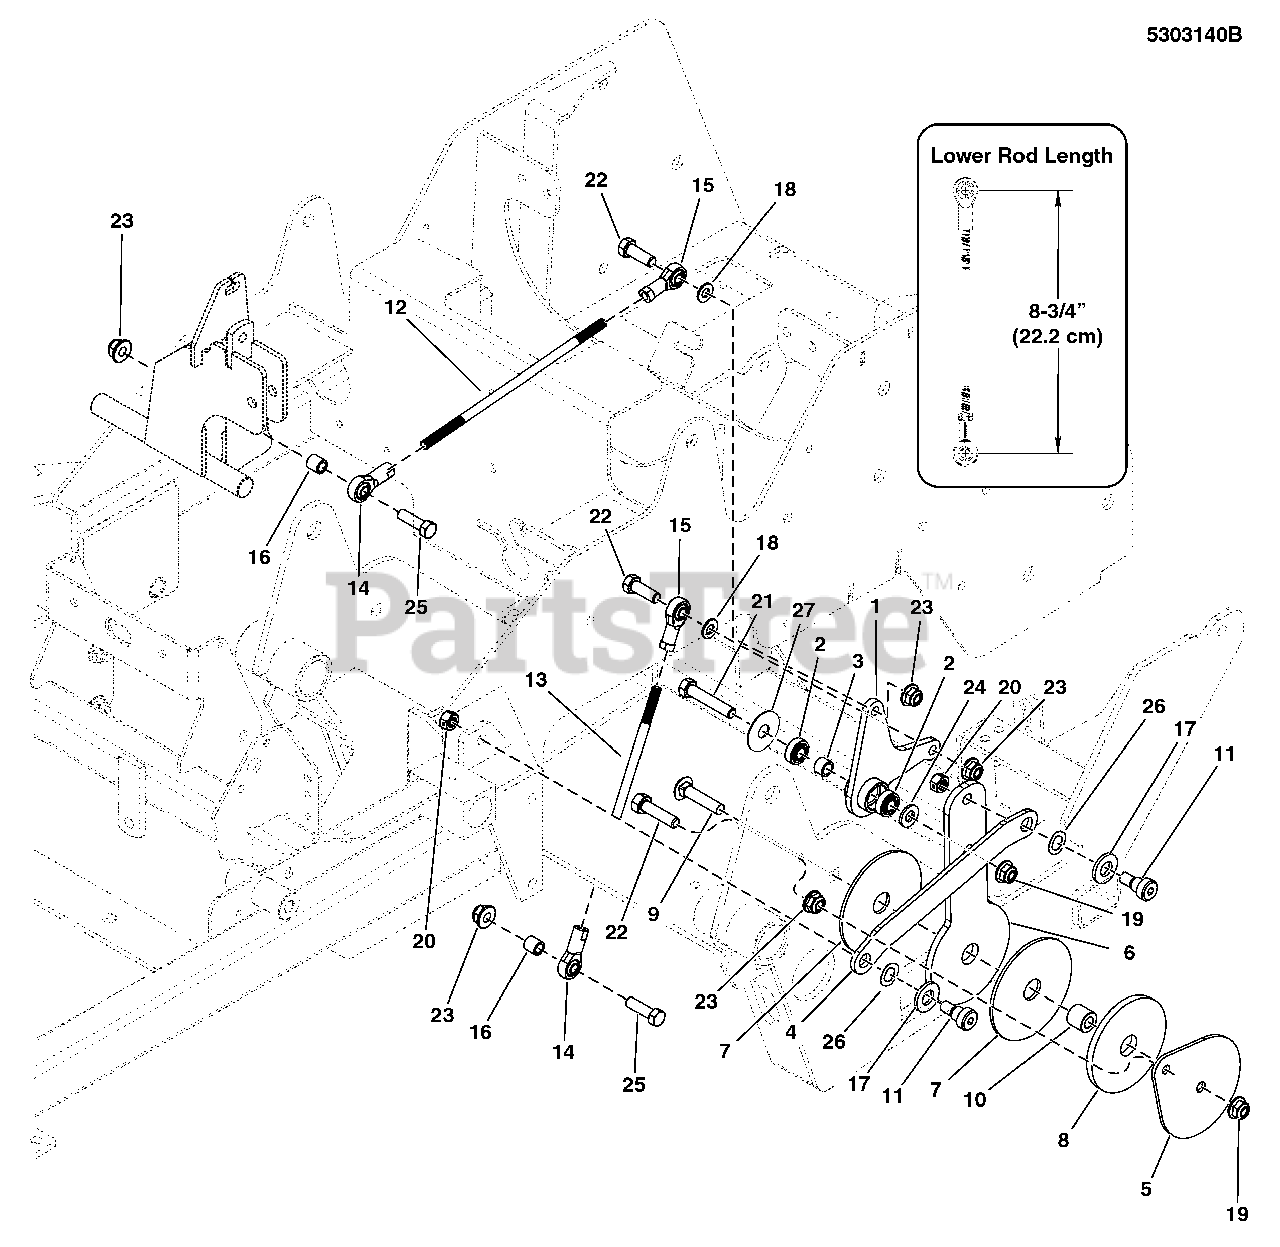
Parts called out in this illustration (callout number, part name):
1	PIVOT, CONTROL SYSTEM
2	BEARING, .375" ID X .875" OD X .341" THK
3	SPACER, .39 X .55 X .38, CZ
4	LINK, CONTROL SYSTEM ARM, IS600 - BLK
5	PLATE, CONTROL SYSTEM LOCK - BLK
6	PLATE, CONTROL SYSTEM ARM - HT
7	PAD, CONTROL SYSTEM
8	PAD, .77 X 3.50 X .25, POLYURETHANE
9	BOLT, 3/8-16 X 1-1/2, CARRIAGE, GD5, CZ
10	SPACER, .39 X .75 X .69, CZ
11	BOLT, 3/8-16 X 3/8, 1/2 SHOULDER
12	ROD, 5/16 X 8.38, LH-RH, CZ
13	ROD, 5/16 X 7.00, LH-RH, CZ
14	BALL JOINT 5/16-24 RH FEMALE STAMPED STL
15	BALL JOINT 5/16-24 LH FEMALE STAMPED STL
16	SPACER, .33 X .50 X .50, CZ
17	WASHER, 1/2 GD9 YZ
18	WASHER, 5/16 SAE
19	NUT, 3/8-16 HEX NYLOCK FLANGE
20	NUT, 3/8-16 HEX SIDE LOCK
21	BOLT, 3/8-16 X 2 GD5 YZ
22	BOLT, 5/16-18 X 1-1/4 GD5 YZ
23	NUT, 5/16-18 HEX NYLOCK FLANGE
24	WASHER, 3/8 GD.9 FLAT
25	BOLT, 5/16-18 X 1-1/2 GD5 YZ
26	WAVE WASHER, 1/2"ID X 087"OD X .01 THK.
